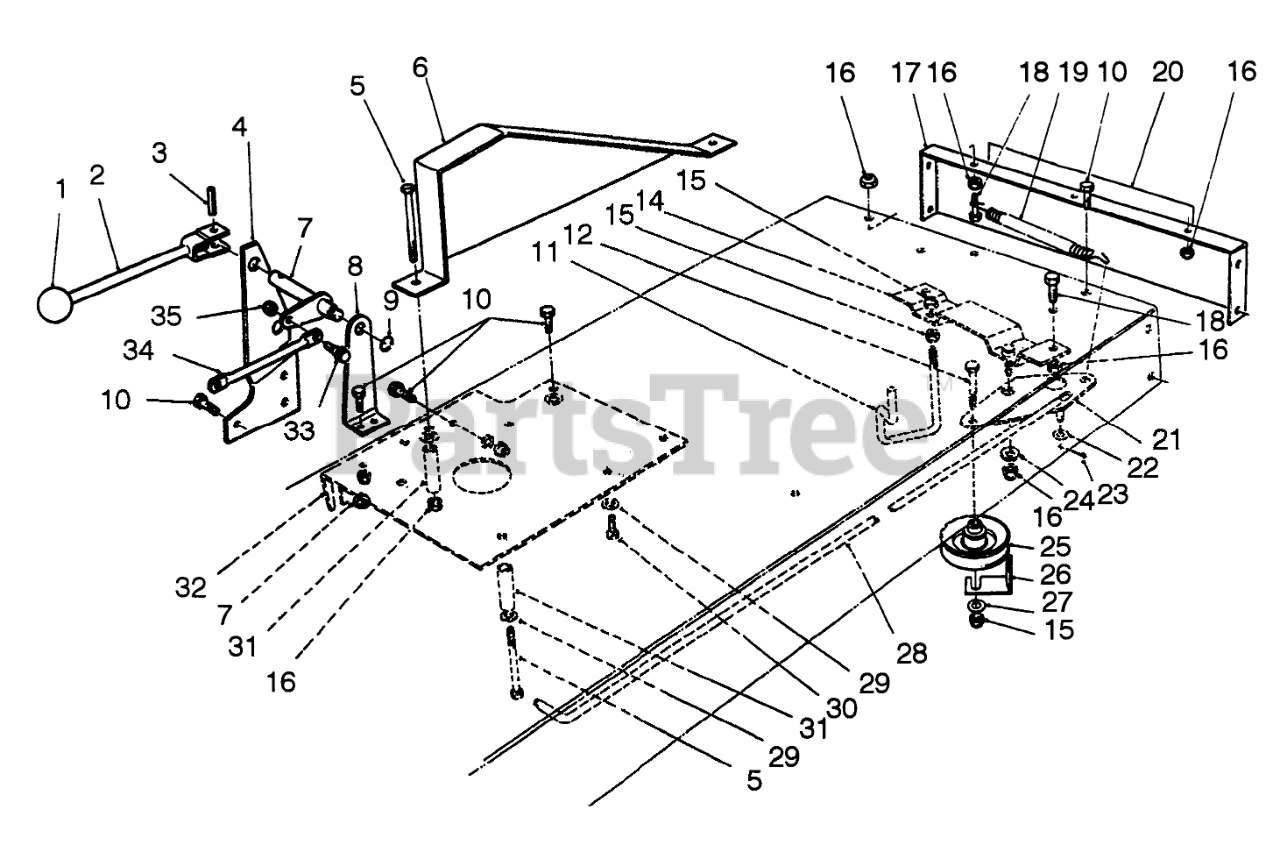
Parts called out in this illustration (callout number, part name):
2	Lever W.A.-Engage
3	PIN-ROLL
4	Pivot-Outer
5	SCREW-HH
6	CHAIN GUARD R
7	PIVOT SHAFT WA
8	Bracket-Pivot, Inner
9	RING-RETAINING, EXTERNAL
10	SCREW-HH
11	BELT GUIDE
12	SCREW-HH
14	TRACT SUPT BRKT WA B
15	NUT-LOCK, NI
16	NUT-LOCK, NI
17	REAR FRAME R
18	SCREW-HH
19	TRACTION SPRING
20	DECAL - REAR FRAME
21	TRACT PIVOT BRKT B
22	WASHER-FLAT
23	PIN-COTTER
24	WASHER-FLAT
25	PULLEY-IDLER
26	RETAINER-BELT
27	WASHER-FLAT
28	TRACTION ROD
29	WASHER-PLAIN
30	SCREW-HH
31	OUTER TUBE SPACER
32	REINF PLATE R
33	SCREW-SHOULDER
34	LINK-BELLCRANK
35	NUT-HEX
